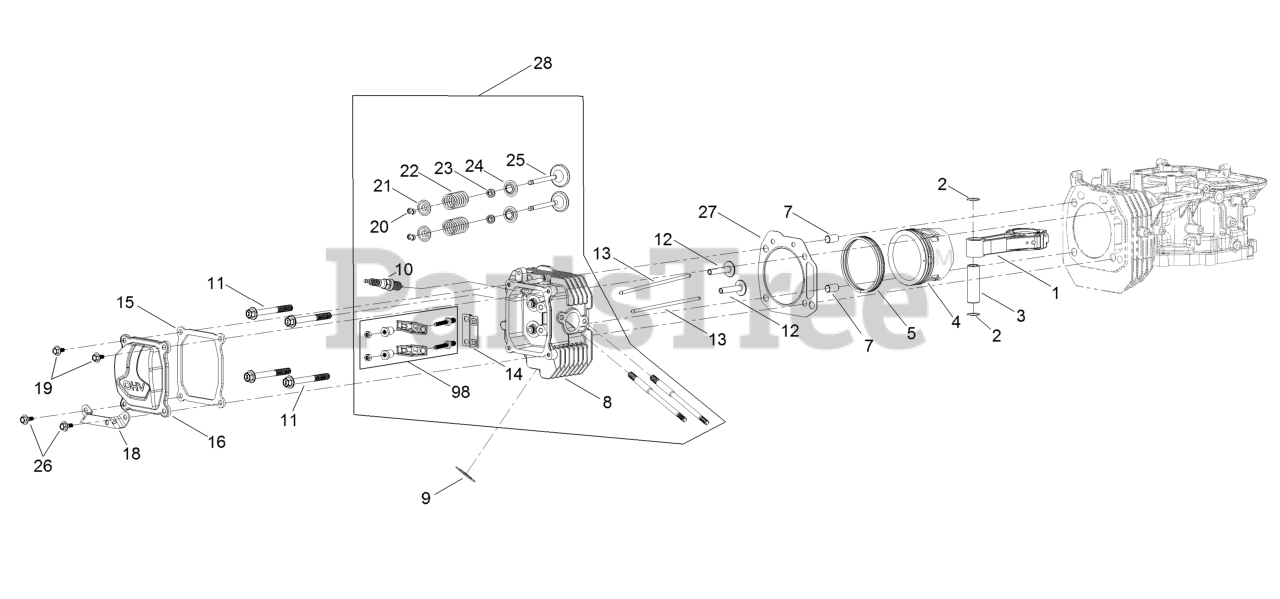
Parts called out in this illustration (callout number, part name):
1	CONNECTING ROD ASM
2	RING-RETAINING, PISTON PI
3	PIN-PISTON
5	RING SET
7	PIN-DOWEL
8	HEAD-CYLINDER
9	GASKET-EXHAUST
10	PLUG-SPARK
11	SCREW-HHF
12	LIFTER-VALVE
13	ROD-PUSH
14	PLATE-GUIDE, PUSH ROD
15	GASKET-COVER, VALVE
16	COVER-VALVE
18	BRACKET-MUFFLER
19	SCREW-SHOULDER, HHF
20	KEEPER-VALVE
21	RETAINER-SPRING, VALVE
22	SPRING-VALVE
23	SEAL-STEM, VALVE
24	SEAT-SPRING, VALVE
25	VALVE SET
26	SCREW-SHOULDER, HHF
27	GASKET-CYCLINDER
28	COMPLETE HEAD ASM
